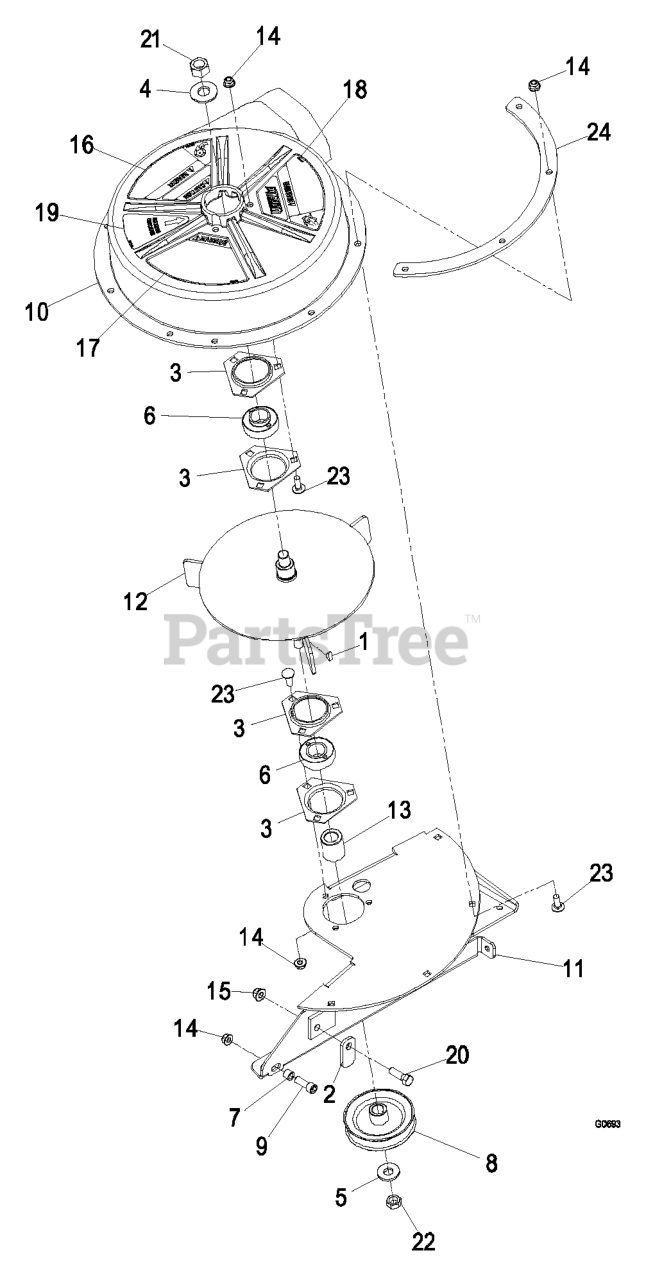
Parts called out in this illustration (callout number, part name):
1	KEY-WOODRUFF
2	LATCH-CATCHER, GRASS
3	HOUSING-FLANGE
4	WASHER-SPRING
5	WASHER-SPRING
6	BEARING
7	BUSHING, LOCATOR
8	SHEAVE-BLOWER
9	SCREW-HSH
10	ASM,BLOWER HOUSING W/DECA
11	WLD,BLOWER FRAME
12	WLD,IMPELLER CT BLOWER
14	NUT-HF, NI
15	NUT-HF, NI
16	DECAL,WARNING LCTUV
17	DECAL,READ/WEIGHT
18	DECAL,WARNING HIGH SPEED
19	DECAL,ROTATION INDICATOR
20	SCREW-HH
21	NUT-HEX
22	NUT-JAM
23	BOLT-CARR
24	Flange, Support
